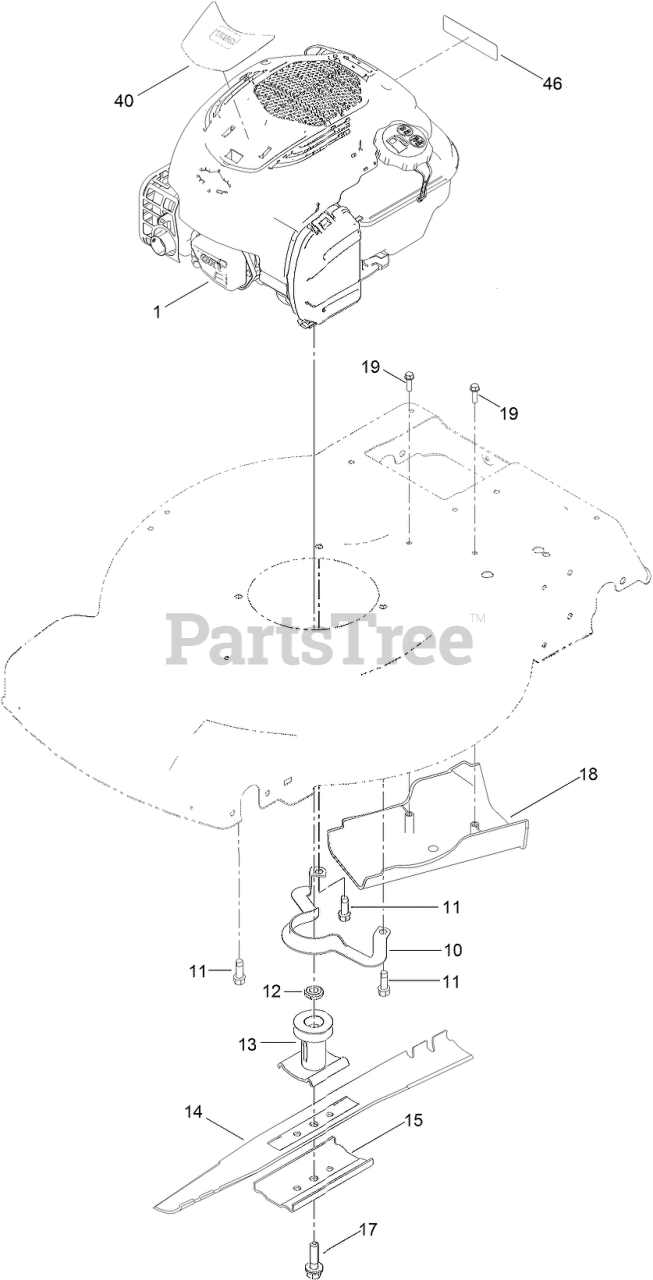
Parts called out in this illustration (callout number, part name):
10	GUIDE-BELT
11	SCREW-TAPTITE
12	SPACER-DRIVER
13	DRIVER-BLADE
14	BLADE-22 INCH
15	SUPPORT-BLADE
17	BOLT-BLADE
18	COVER-BELT
19	SCREW-HWH
40	DECAL-SHROUD
46	DECAL-ARRESTOR, SPARK
